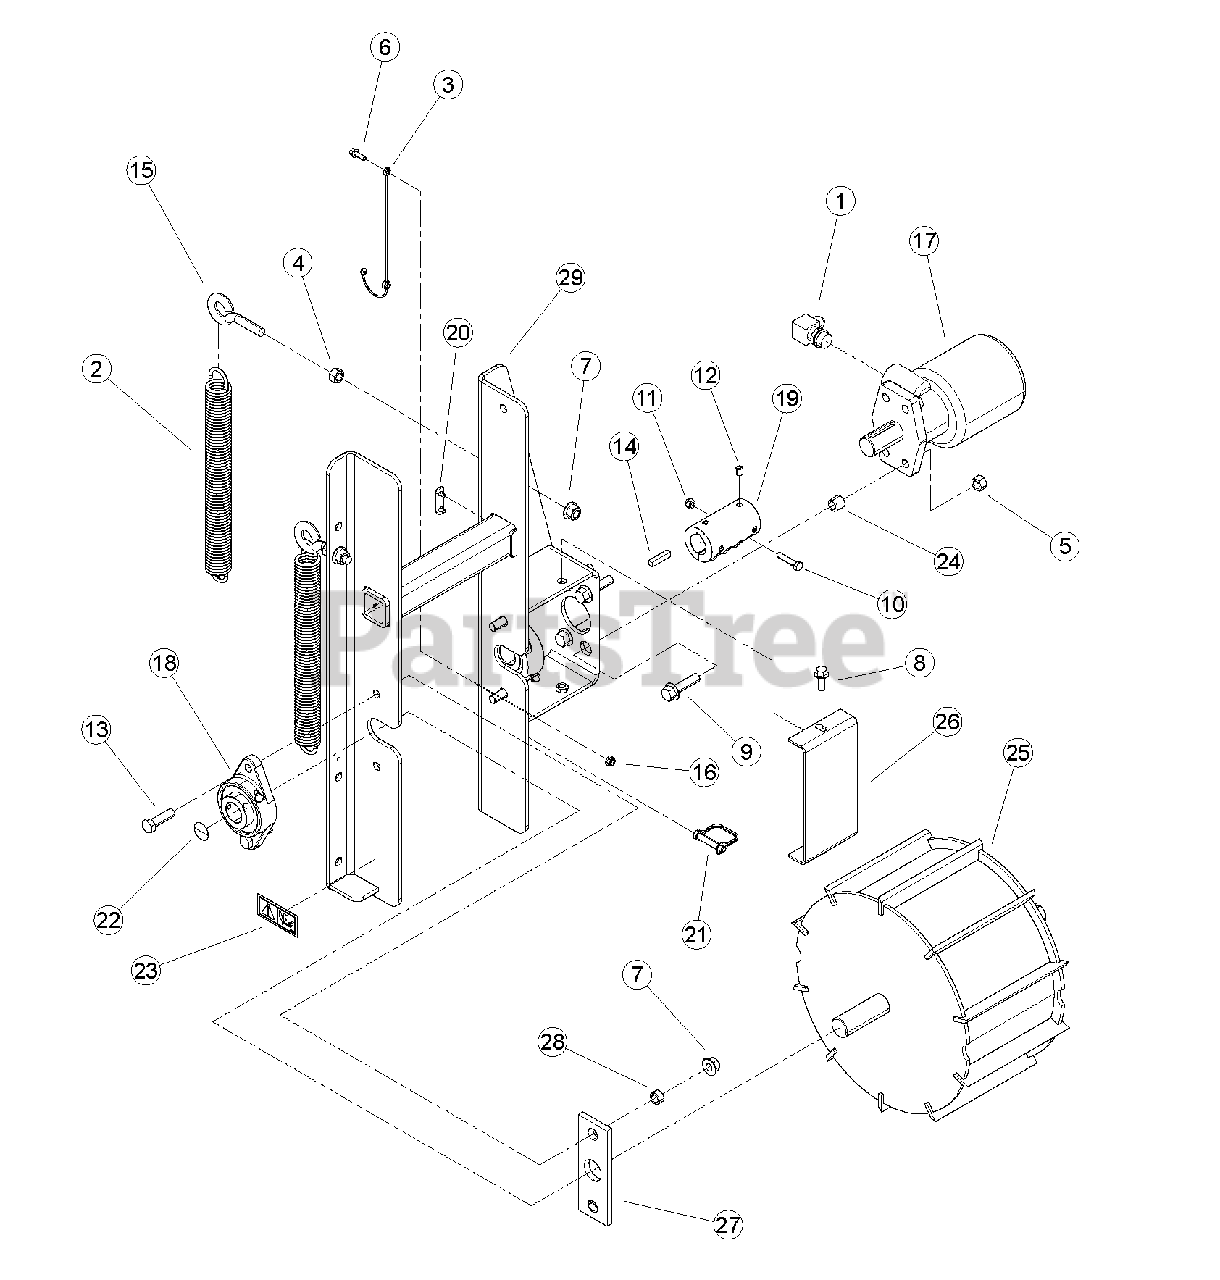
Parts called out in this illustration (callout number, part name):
1	ADAPTER, -10MORING/-8MJIC 90 DEG
2	SPRING, EXTENSION
3	LANYARD, NYLON
4	NUT, 1/2" HEX NC ZP
5	NUT, 1/2" CENTERLOCK GRB ZP
6	BOLT, 1/4-20 X 3/4 HWH GR5 CZP
7	NUT, 1/2-13 NYLOCK FLANGE
8	BOLT, 3/8 X 1 FLANGE NC
9	BOLT, 1/2-13 X 2 HWH GR5 CZP
10	BOLT, 5/16 X 1-1/2 GR5 HEX CPS ZP
11	NUT, 5/16" NE NYLOCK ZP
12	SET SCREW, 3/8 X 1/2 CUP PT SKT
13	BOLT, 1/2 X 1 3/4 GR5 HCPS NC ZP
14	KEY, 5/16 X 1-1/2 SQUARE
15	EYEBOLT, 1/2 X 2" ZP
16	NUT, 1/4-20 NYLOCK-FLANGE
17	MOTOR, 45 CU IN HYDRAULIC
18	BEARING, 1-1/4" DIA 2 BOLT FLANGE
19	COUPLER, 1-1/4 SHAFT
20	WEAR PAD, STD. SPRING HD FRONT
21	PIN, SNAP 3/8 X 1-1/2 USABLE LGH
22	DECAL, ROTATING SHAFT
23	DECAL, CRUSHING ISO
24	SPACER, 0.75 X 0.620
25	WELDMENT, TOP GRAB ROLLER
26	SHIELD, COUPLER
27	BEARING, SLIDE
28	SPACER, .75 OD X .5 ID X .37
29	WELDMENT, ROLLER SLIDE
